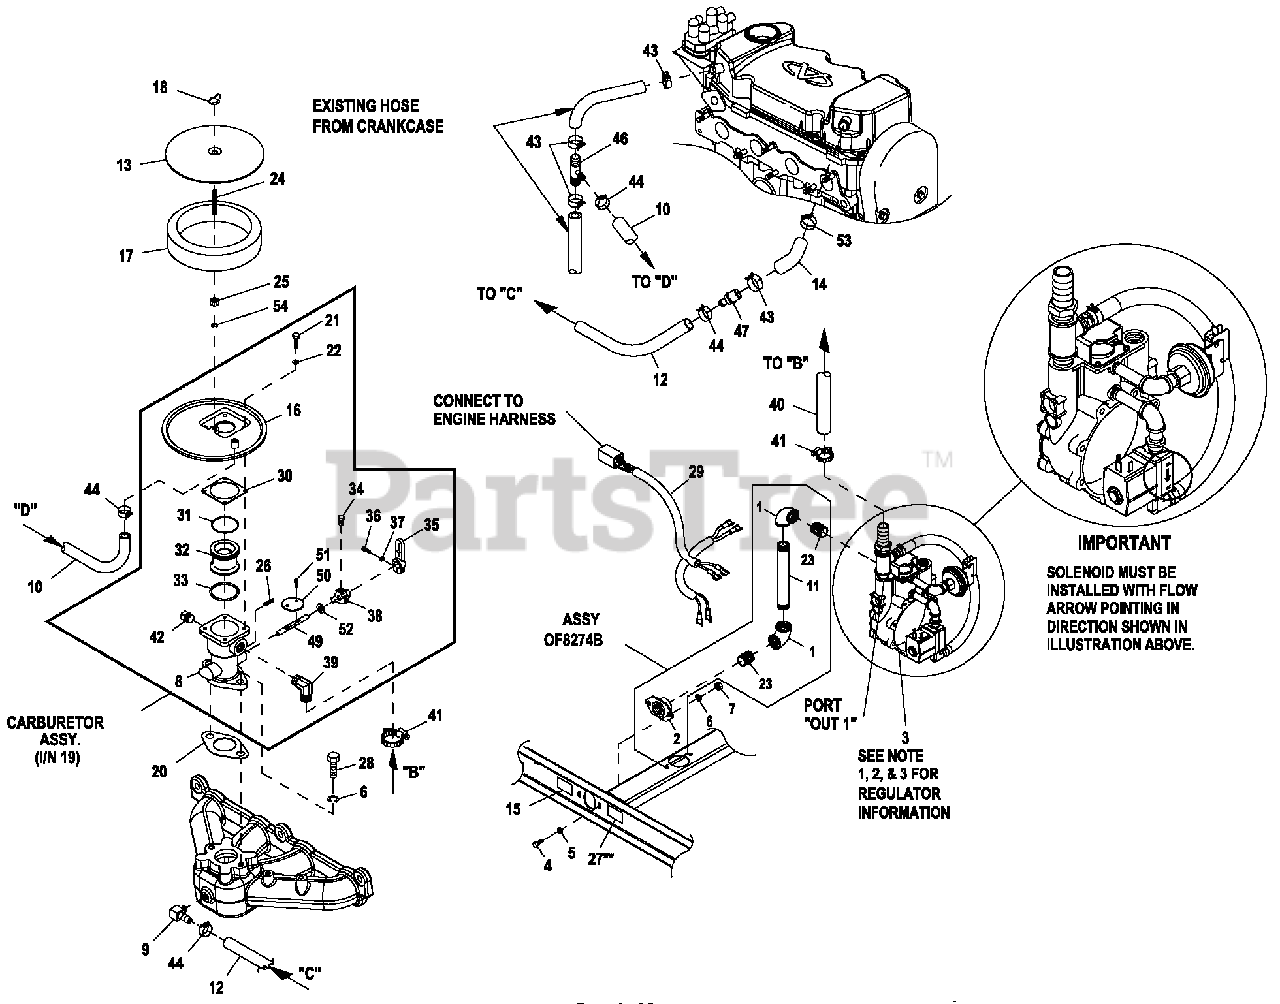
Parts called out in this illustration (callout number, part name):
1	ELBOW 90D 3/4 NPT
2	FLANGE FUEL INLET
3	FUEL REG. REWORK 1,6L 3600 '07 (3600RP M )
4	SCREW HHC M8-1.25 X 20 G8.8
5	WASHER FLAT 5/16 ZINC
6	WASHER LOCK M8-5/16
7	NUT HEX M 8-1.25 G8 YEL CHR
8	BODY CARBURETOR ASSEMBLY
9	BARBED EL 90 1/8 NPT X 3/8
10	HOSE 3/8 ID SINGLE BRAID (16" LG)
11	NIPPLE PIPE 3/4 NPT X 6
12	HOSE 3/8 ID SINGLE BRAID (12" LG)
13	COVER AIR CLEANER
14	HOSE BREATHER 1.6L
15	DECAL INLET PRESSUR
16	ADAPTER CARB. TO AIR CLNR
17	FILTER ELE M ENT
18	NUT WING 1/4-20 NYLK
19	ASSY CARBURETOR 1.6L 3600RP M
20	CARBURETOR GASKET
21	SCREW PPHM M 5-0.8 X 12 ZNC
22	WASHER LOCK M5
23	NIPPLE CLOSE 3/4X1.375
24	STUD TH 1/4-20 X 3 G2 ZNC FULL
25	NUT HEX 1/4-20 STEEL
26	PIN SPRING 3/16X5/8
27	DECAL FUEL INLET NG
28	SCREW HHC 5/16-18X1 G5
29	HARNESS FUEL JUMPER SINGLE REG
30	GASKET AIR CLEANER ADAPTER
31	O-RING 2-028 1.38 X 1.50 X .06
32	VENTURI 20 M M (3600RPM)
33	O-RING 29.82X2.62
34	SCREW THROTTLE PIN STOP
35	THROTTLE AR M REWORK
36	SCREW HHM #10-32X5/8
37	WASHER LOCK #10
38	LEVER THROTTLE STOP
39	BARBED EL 90 3/8 NPT X 5/8
40	HOSE 5/8 ID LPG & NG (12" LG)
41	CLA MP HOSE #10.56-1.06
42	PLUG STD PIPE 1/4 STEEL SQ HD
43	CLA MP HOSE BAND 1.0"
44	CLA MP HOSE BAND .63
46	HOSE BARB REDUCR TEE 3/4"-3/8"
47	PCV VALVE 2.5L FORD
49	SHAFT THROTTLE 1.5L
50	THROTTLE VALVE PLATE 27MM
51	SCREW RHMS 6-32 X 1/4 ZINC
52	SEAL SHAFT COVER
53	CLA MP HOSE BAND .88"
54	WASHER LOCK M 6-1/4
